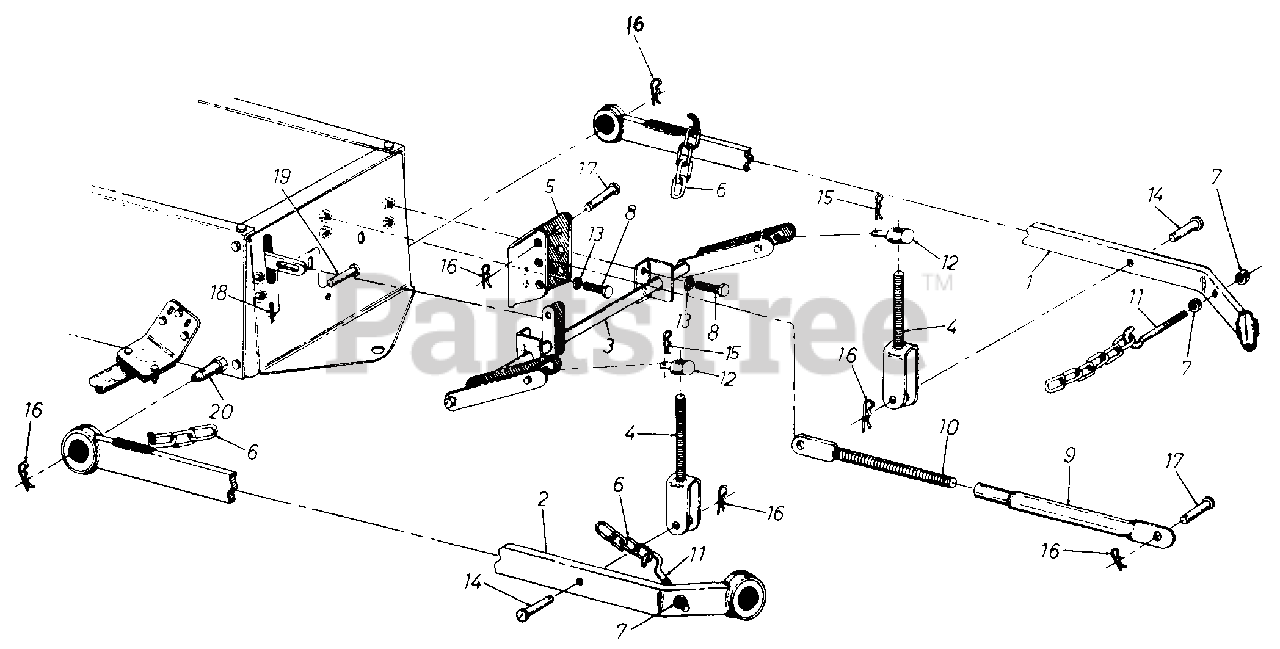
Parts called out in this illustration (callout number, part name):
1	Draft Bar Assembly-R.H.
2	Draft BarAssembly-L.H.
6	Chain 201inks
7	Hex Cent. L.-Nut 7/16-14 Thd.
8	Hex Bolt 5-3/8-16 x 1 Lg. Grade 5
10	Clevis Screw
11	Hitch Chain Hook
12	Clevis Pin
13	L.-Wash. 3/8 " I.D. *
14	Clevis Pin 5/8 Dia. x 1.66 Lg.
15	Hairpin
16	Hairpin
17	Clevis Pin 5/8 Dia. x 2.4 Lg.
18	Cotter Pin 1/8 Dia. x 1-1/4 Lg.*
19	Clevis Pin
20	Link Clevis Pin
